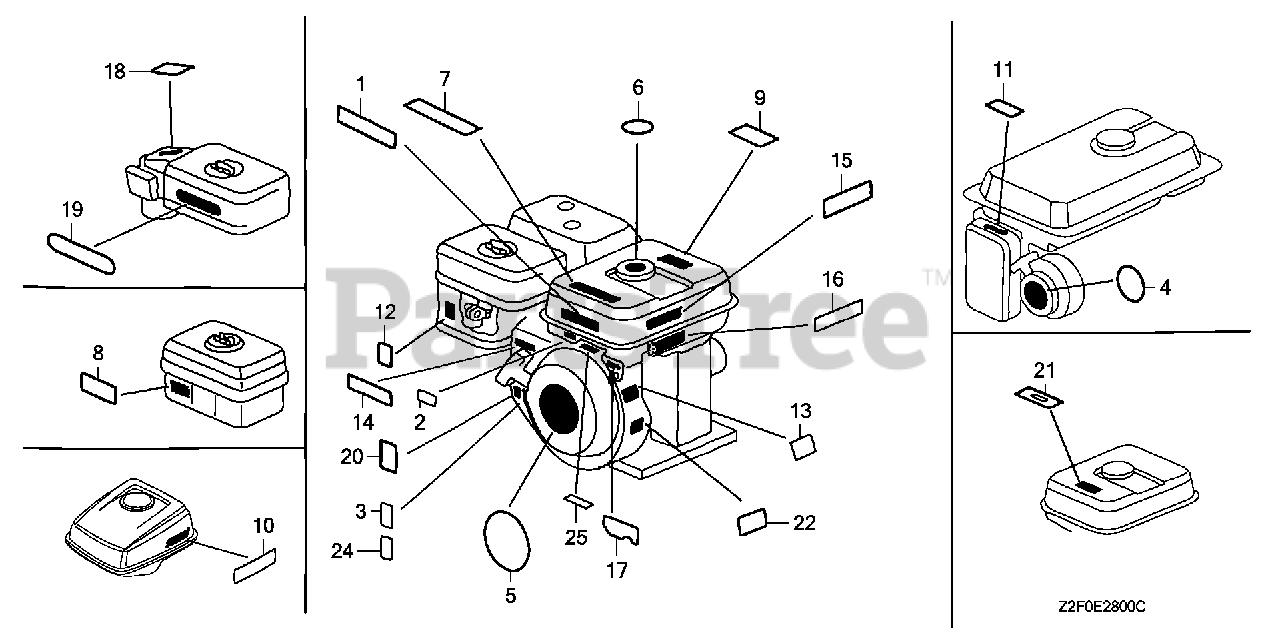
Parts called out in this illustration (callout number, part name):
5	EMBLEM (GX160)
12	MARK, CHOKE
15	MARK, OIL ALERT (ENGLISH)
